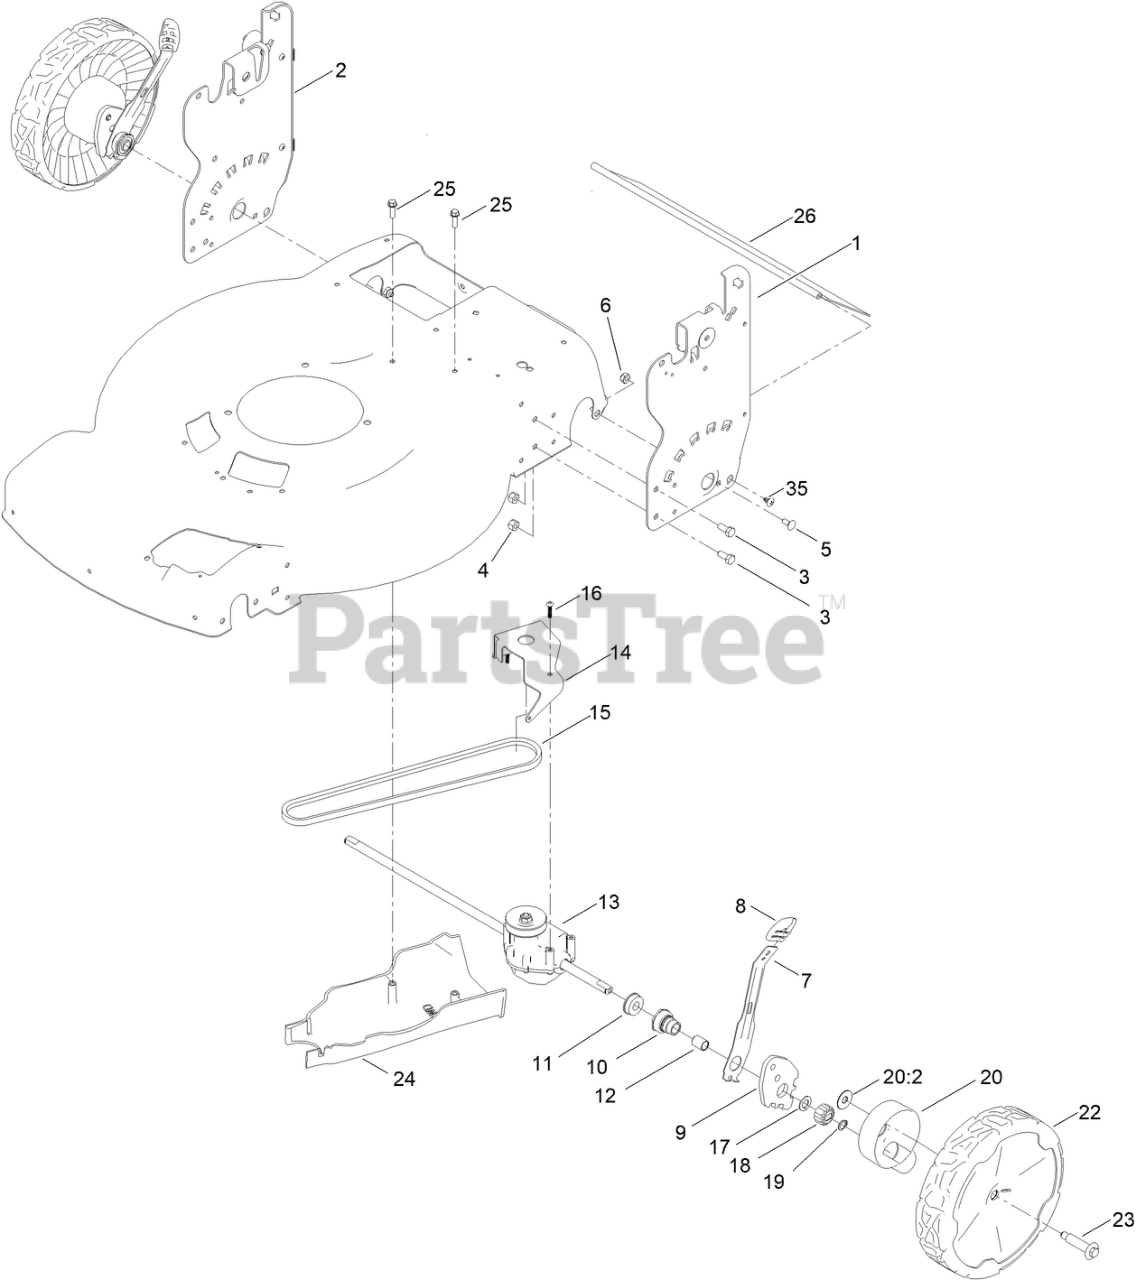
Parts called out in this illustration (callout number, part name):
1	PLATE-HOC, LH (ISO)
2	PLATE-HOC, RH (ISO)
3	SCREW-HH
4	NUT-LOCK, NI
5	SCREW-CARR
6	NUT-LOCK, NI
7	ARM-SPRING
8	KNOB-LEVER, HOC
9	ARM-PIVOT, REAR
10	RETAINER-BUSHING, HOC
11	BEARING-BALL
12	BUSHING-SLEEVE
13	TRANSMISSION-RWD
14	BRACKET-TRANSMISSION
15	V-BELT
16	SCREW-PLASTITE
17	WASHER-THRUST
18	GEAR-PINION, 15T
19	RING-RETAINING
20	ASM-COVER, GEAR (DK GRAY)
20:2	WASHER-STEPPED
22	ASM-9.65" WHEEL, GEARED
23	WHEEL BOLT
24	COVER-BELT, RWD
25	SCREW-HWH
26	SHIELD-TRAILING
35	SCREW-THD
